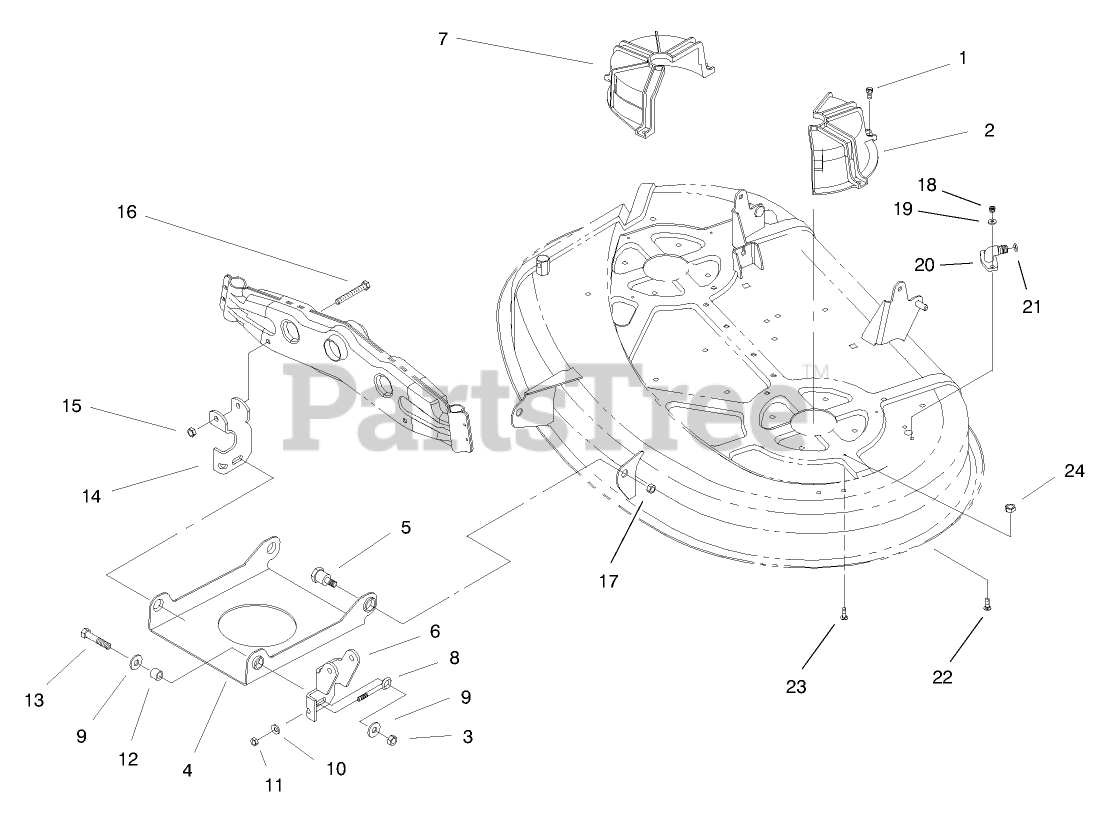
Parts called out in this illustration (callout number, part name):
1	SCREW-HWHTF
2	GUIDE-BELT, LH
3	NUT-LOCK, NI
4	PAN-DECK SUSPENSION, FRONT
6	BRACKET-SUSPENSION, LH
7	GUIDE-BELT, RH
8	SCREW-ADJUSTING
9	WASHER-HARDENED
10	WASHER-FLAT
11	NUT-LOCK, NI
12	SPACER
13	SCREW-HH
14	BRACKET-SUSPENSION, RH
15	NUT-LOCK, NI
16	SCREW-HH
17	NUT-LOCK, NI
18	NUT-LOCK, NI
19	WASHER-FLAT
21	O-RING
22	BOLT-CARR
23	SCREW-HH
24	NUT-LOCK, NI
